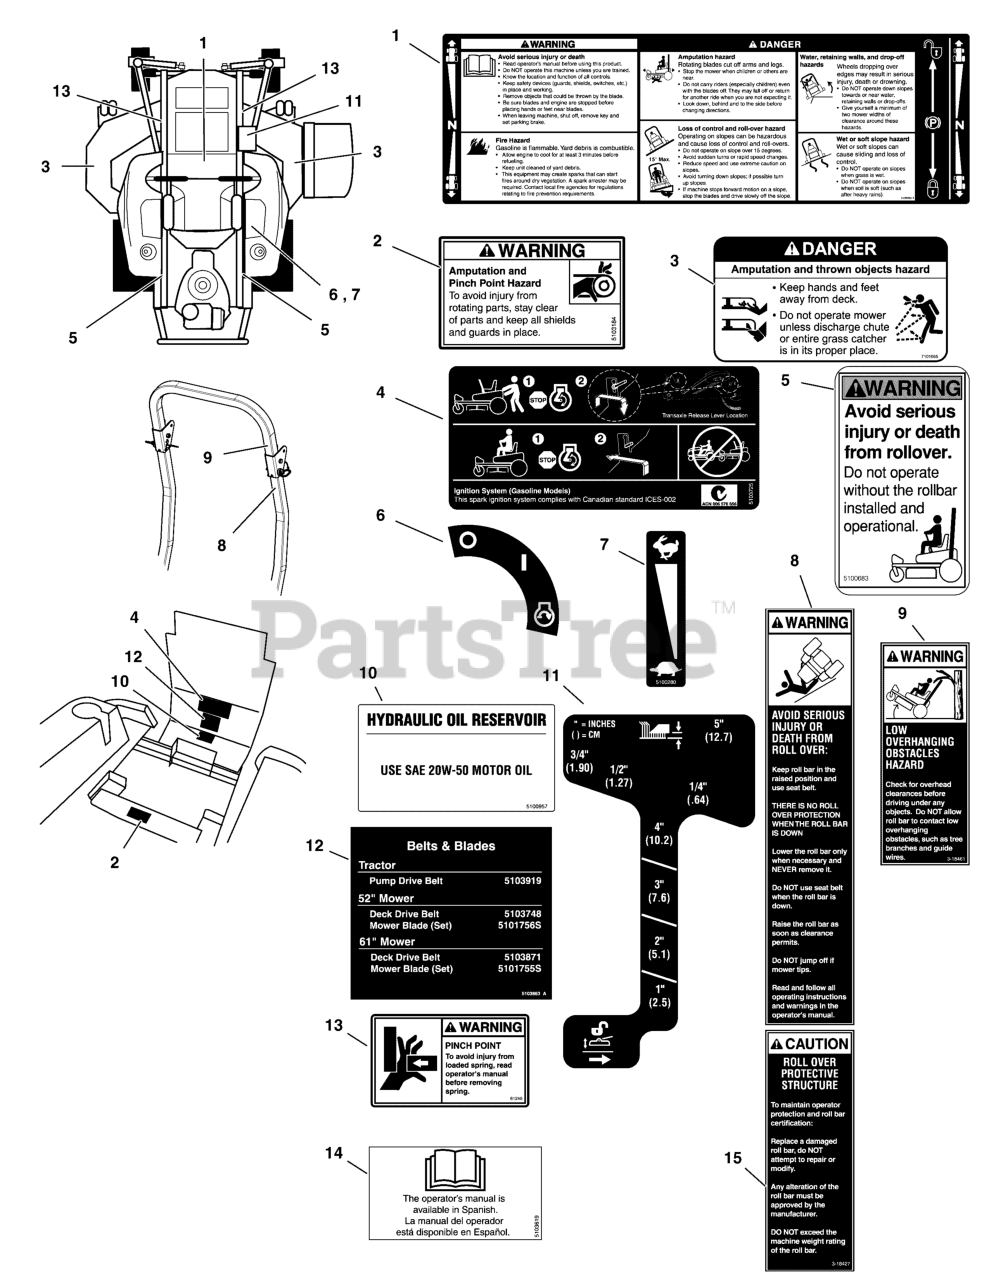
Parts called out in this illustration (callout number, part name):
1	DECAL, MAIN SAFETY
2	DECAL, WARNING, HAND IN BELT, ENG ONLY
3	DECAL, DANGER DO NOT OPERATE W/O DEFLECT
4	DECAL, TRANSAXLE RELEASE, 600/700
5	DECAL, Warning, ROLL BAR
6	DECAL, IGNITION CONTROL
7	DECAL, Throttle Control
8	DECAL, WARNING, FOLDING ROLL BAR
9	DECAL, WARNING OVERHANG, ROPS (SV)
10	DECAL, HYDRAULIC OIL, SAE 20W50
11	DECAL, CUT HEIGHT, IS700/ZTS700
12	DECAL, BELT & BLADE, S125XT
13	DECAL, Pinch Point
14	DECAL, MANUAL AVAILABLE IN SPANISH
15	DECAL, CAUTION, FOLDING ROLL BAR
